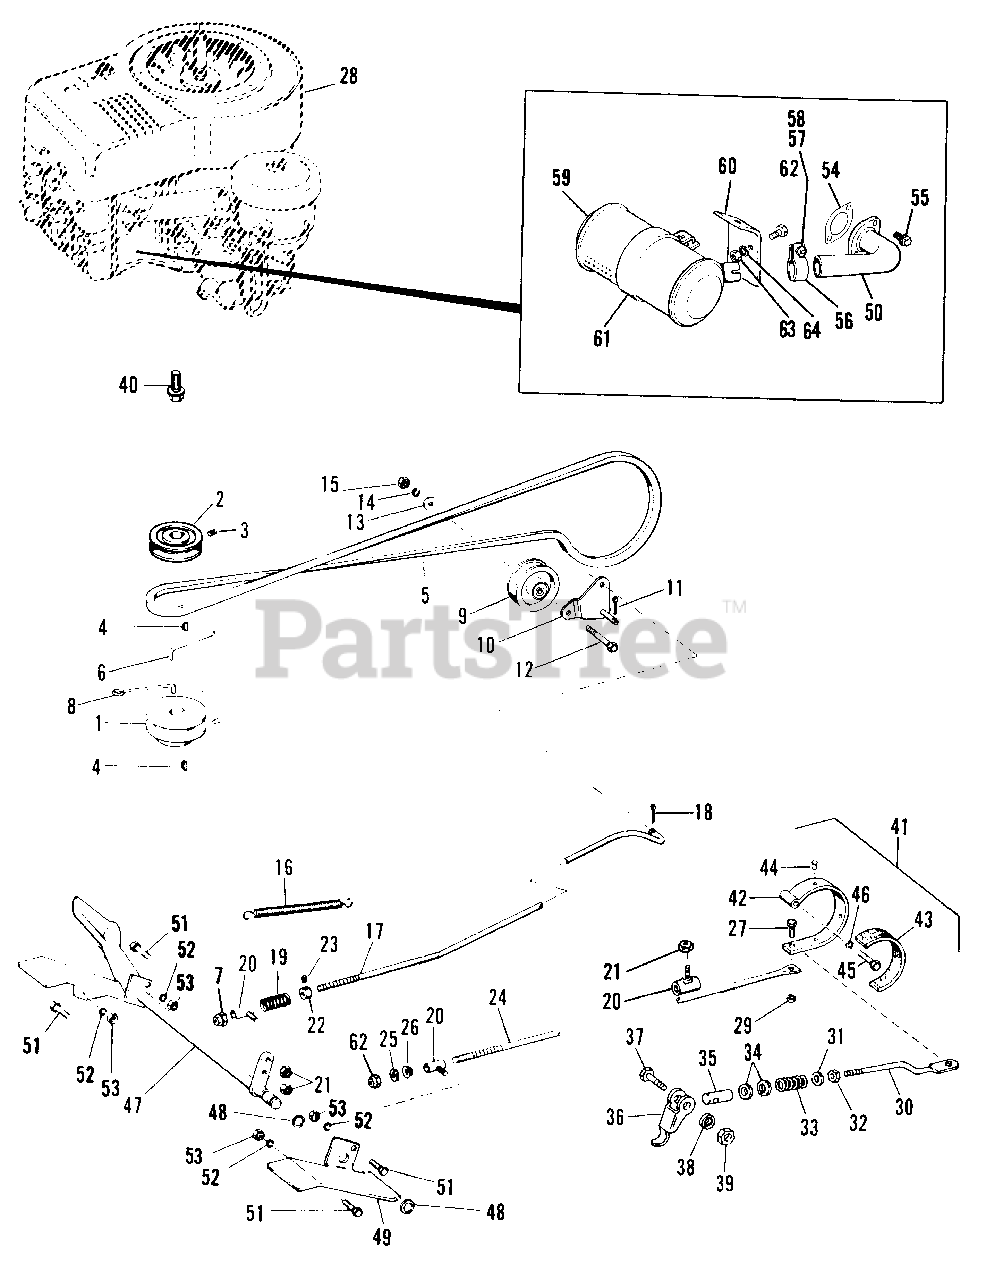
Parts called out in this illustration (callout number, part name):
1	Pulley, Engine, Large
3	Screw, Set, 5/16"-18 x 5/16" lg.
5	Belt,"V" Drive
6	Stop, Belt
7	Nut, Eiastic, Stop, 5/16-18
8	Stop, Belt
9	Puller, Idler
10	Bracket Assembly, Pulley
11	Pin, Cotter, 1/8" x 3/4" lg.
12	Capscrew, Hex, 3/8"-16 x 1-1/4" lg.
13	Washer, Plain, 5/16"
14	Lockwasher, 3/8"
15	Nut, Hex, Full, 3/8"-16
16	Spring, Return
17	Rod, Clutch
18	Pin, Coner, 1/8" x 3/4" lg.
19	Spring, Compression
20	Guide Assembly, Rod
21	Nut, Hex, Full, Lock, 5/16"-18
22	Collar, Set
23	Screw, Set, 1/4"-20 x 3/8" lg.
24	Rod, Brake
25	Washer, Plain 3/8" lg.
26	Spring, Conical
27	Capscrew, Hex, 1/4"-20 x 3/4" lg.
29	Nut, Hex, Full, Lock, 1/4"-20
30	Rod, Parking Brake
31	Washer, Plain, 1/4"
32	Nut, Hex, Full, 5/16"-18
34	Washer, Plain, 1/2"
36	Lever, Parking Brake
37	Capscrew, Hex, 1/4"-20 x 1-1/4" lg.
38	Lockwasher, Double, 1/4"
39	Nut, Hex, Full, Lock 1/4"-20
40	Capscrew, Hex, Special 3/8"-16 x 1-1/4" lg.
41	Band Assembly, Brake
42	Band, Brake
43	Lining, Brake
44	Rivet, #7 x 1/4" lg.
45	Capscrew, Hex, 3/8"-16 x 1-1/2" lg.
46	Lockwasher, 3/8"
47	Shaft Assembly, Clutch
48	Ring, "E"
49	Foot Rest, L.H.
50	Pipe, Exhaust
51	Capscrew, Hex, 3/8"-16 x 3/4" lg.
52	Lockwasher, 3/8"
53	Nut, Hex, Full, 3/8"-16
55	Screw, Hex, "Whiz Lock" 5/16"-18 x 1-1/42" lg.
57	Capscrew, Hex, 5/16"-18 x 1-1/4" lg.
58	Nut, Hex, Full, 5/16"-18
60	Bracket, Muffler
62	Nut, Elastic, Stop, 5/16-18
64	Lockwasher, 5/16"
